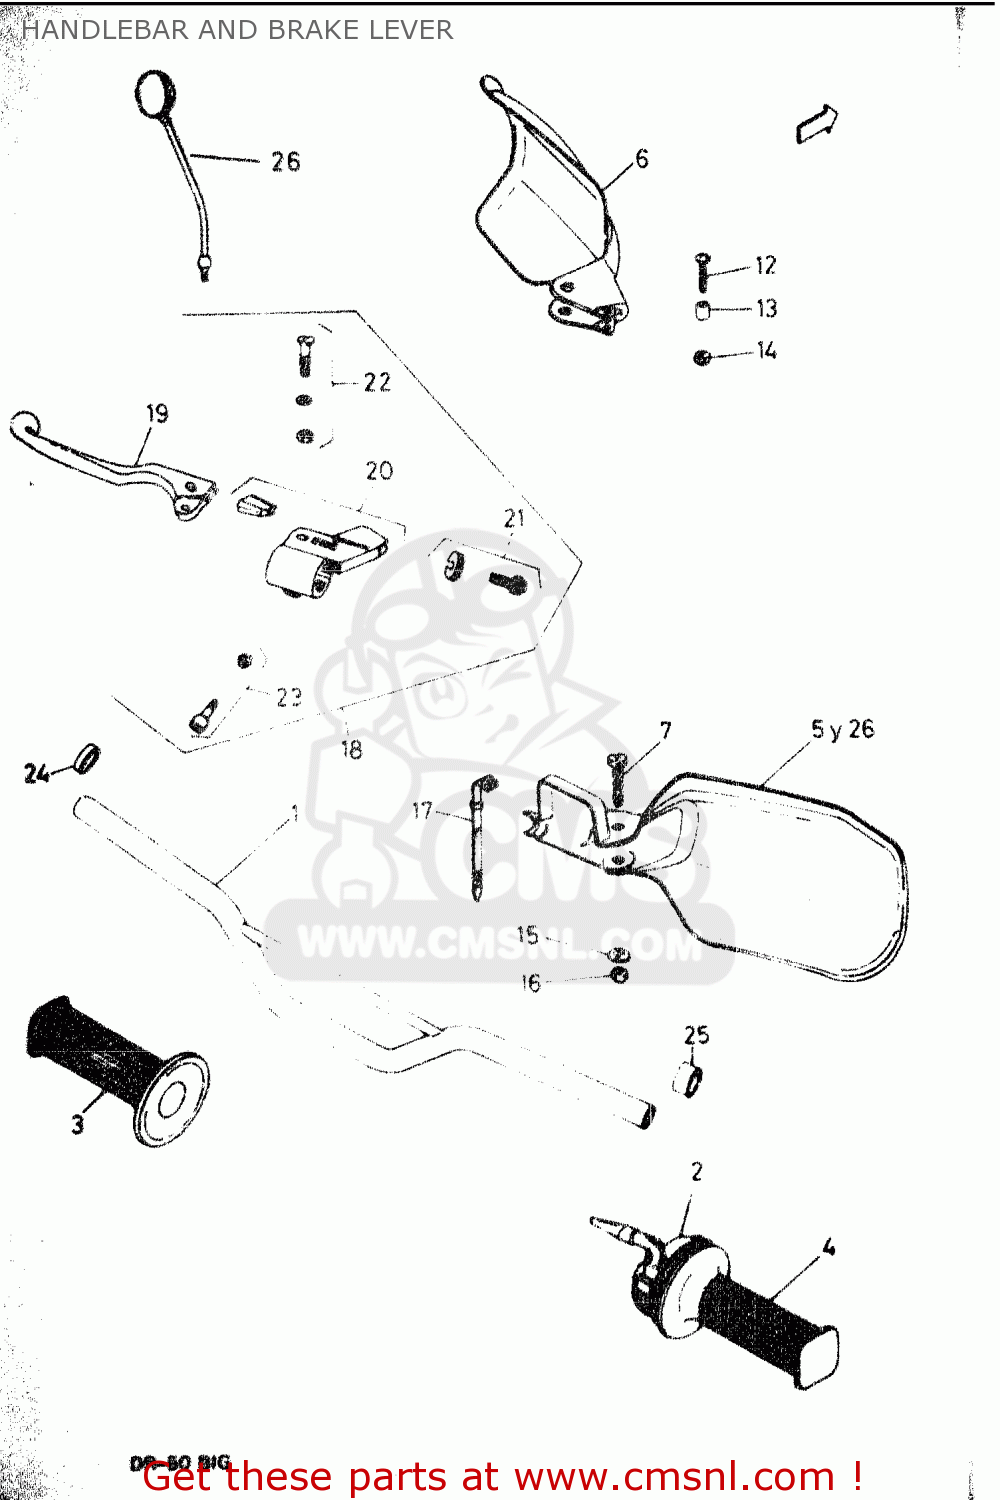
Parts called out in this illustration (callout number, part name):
1	HANDLEBAR (BLACK)
2	CASE ASSY, THROTTLE
3	GRIP, LH
4	GRIP, RH
5	GUARD, KNUCKLE RH (BLUE)
6	GUARD, KNUCKLE RL (BLUE)
7	SCREW M6X45 DIN 84
12	SCREW AM 5X20 DIN 7985
13	SPACER
14	NUT M5 DIN 934
15	WASHER B6 DIN 125
16	NUT M6 DIN 985
17	CLAMP L=170
18	LEVER ASSY RL
19	LEVER RL
20	GRIP SUPPORT RL
21	SLEEVE NUT
22	SCREW JET
23	SCREW JET
24	SPACER
25	SPACER
26	MIRROR ASSY
